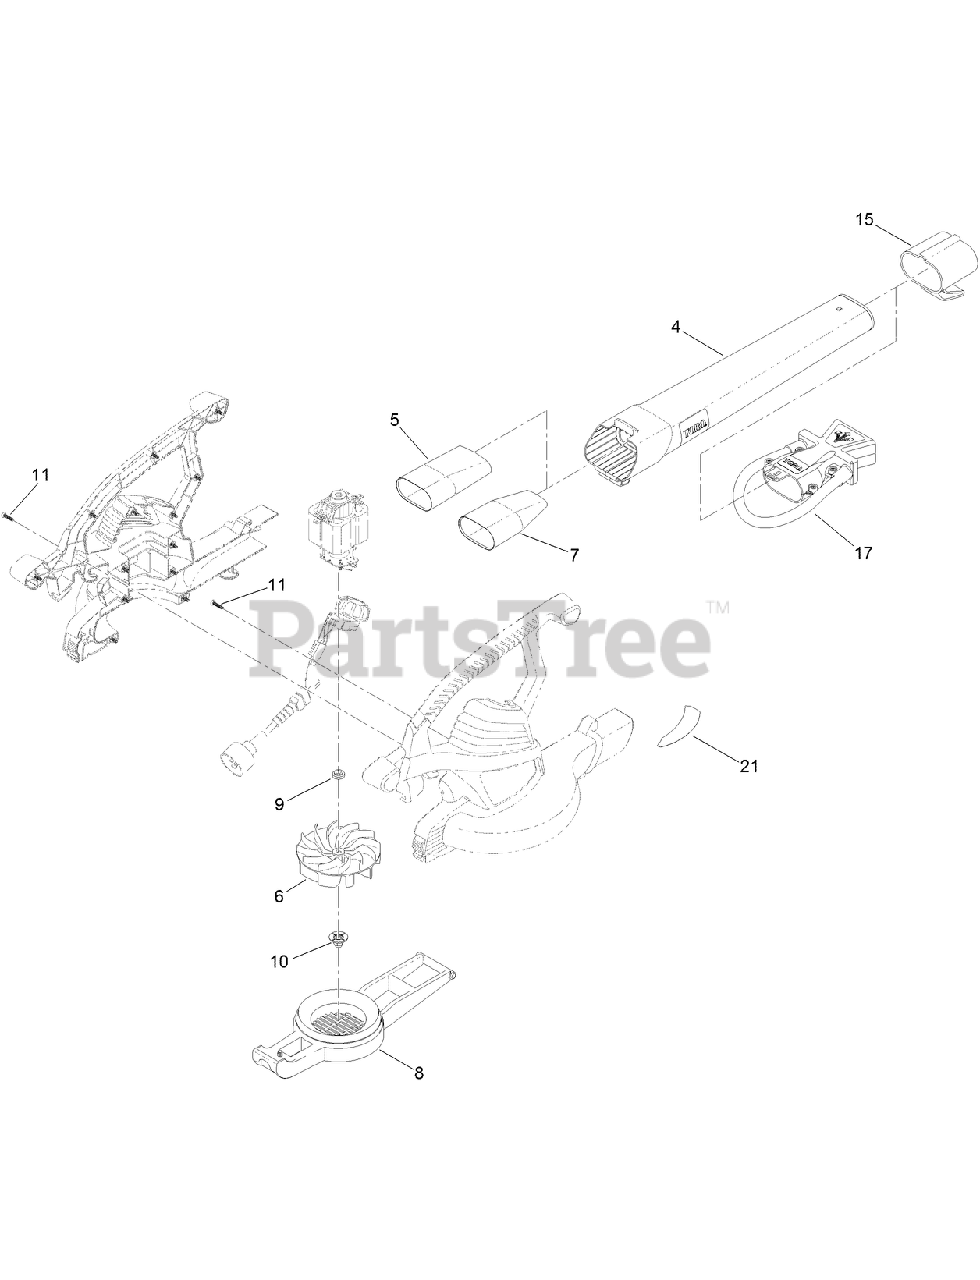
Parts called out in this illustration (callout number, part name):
4	TUBE-BLOWER
5	TUBE-INSERT
7	INSERT-TUBE, MPH
8	COVER-INLET
9	BUSHING-MOTOR
10	NUT-IMPELLER
11	SCREW-PPH
15	ADAPTER-WRAP, CORD
17	OSCILLATOR NOZZLE ASM
21	DECAL-SHREDDING
